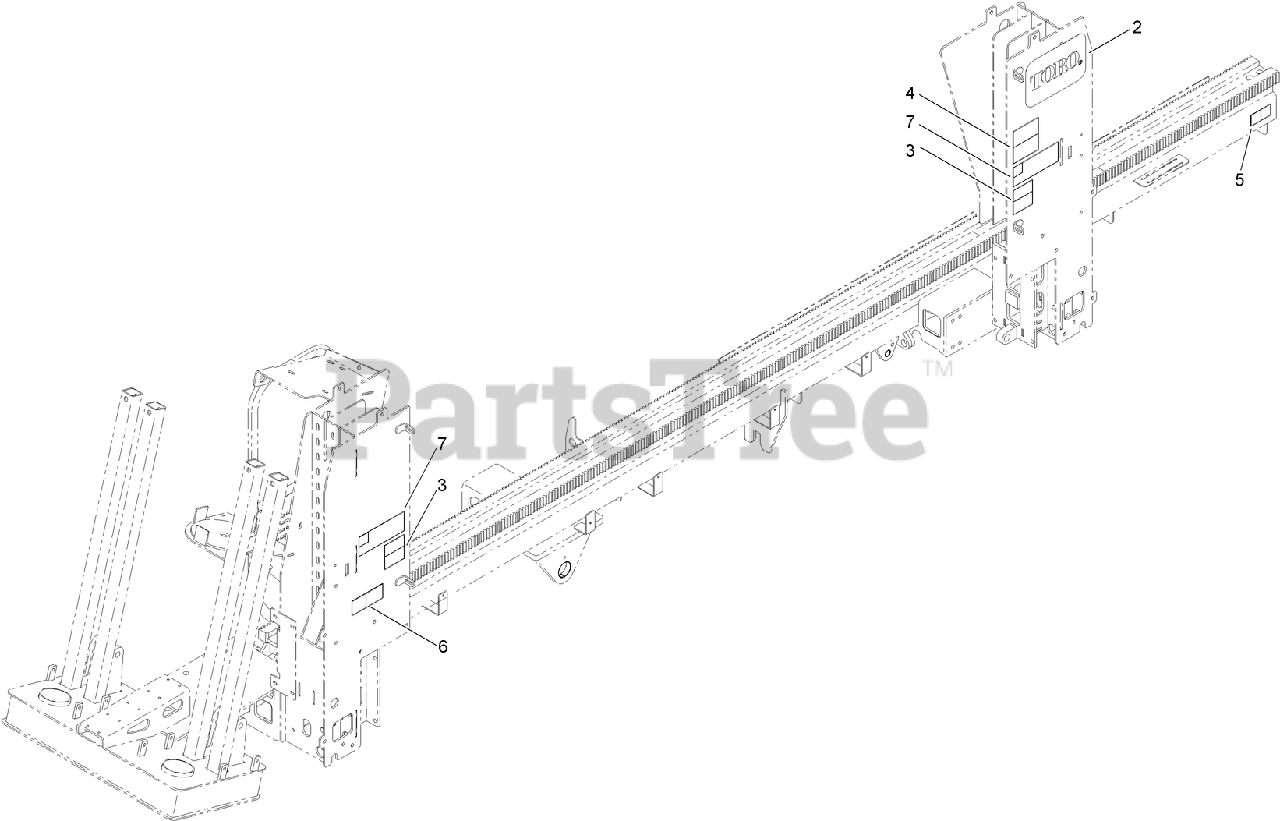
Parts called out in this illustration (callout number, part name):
3	DECAL-WARNING, CRUSHING
4	DECAL-SHOCK DANGER
5	DECAL-DANGER, CRUSHING
6	DECAL-WARNING, HYDRAULIC PRESSURE
7	DECAL-DANGER, HAZARDOUS AREA
